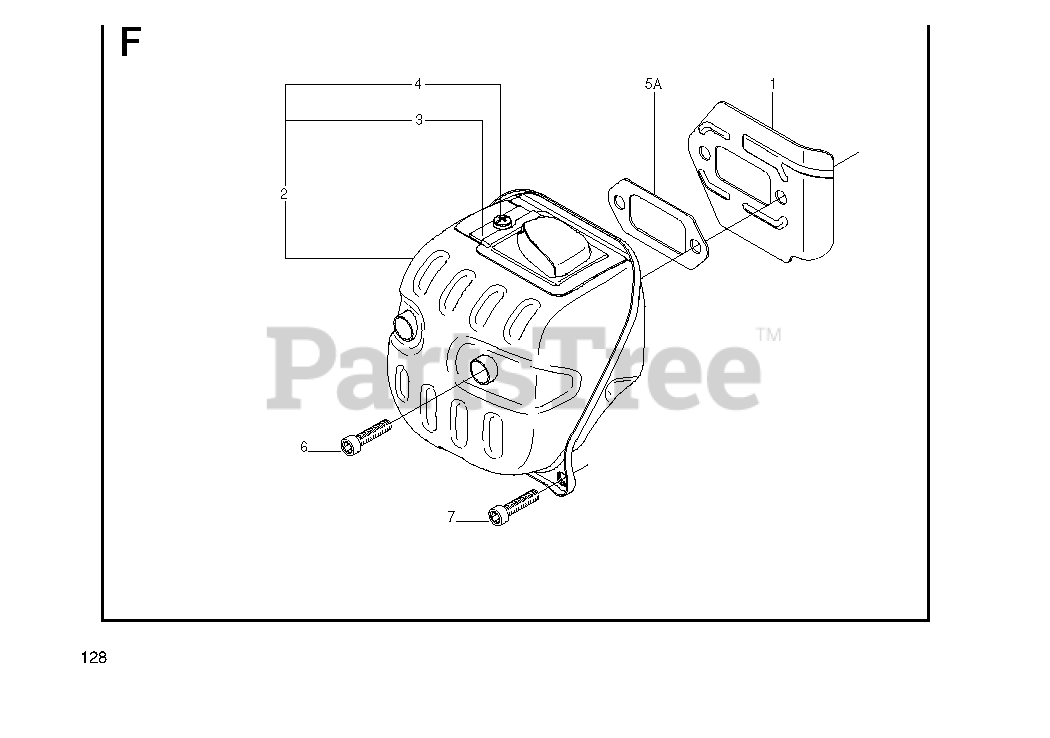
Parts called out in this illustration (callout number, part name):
1	CONDUCTOR
2	MUFFLER ASSY (FF CE)
5	GASKET SET
6	SCREW MC6S 6X20
